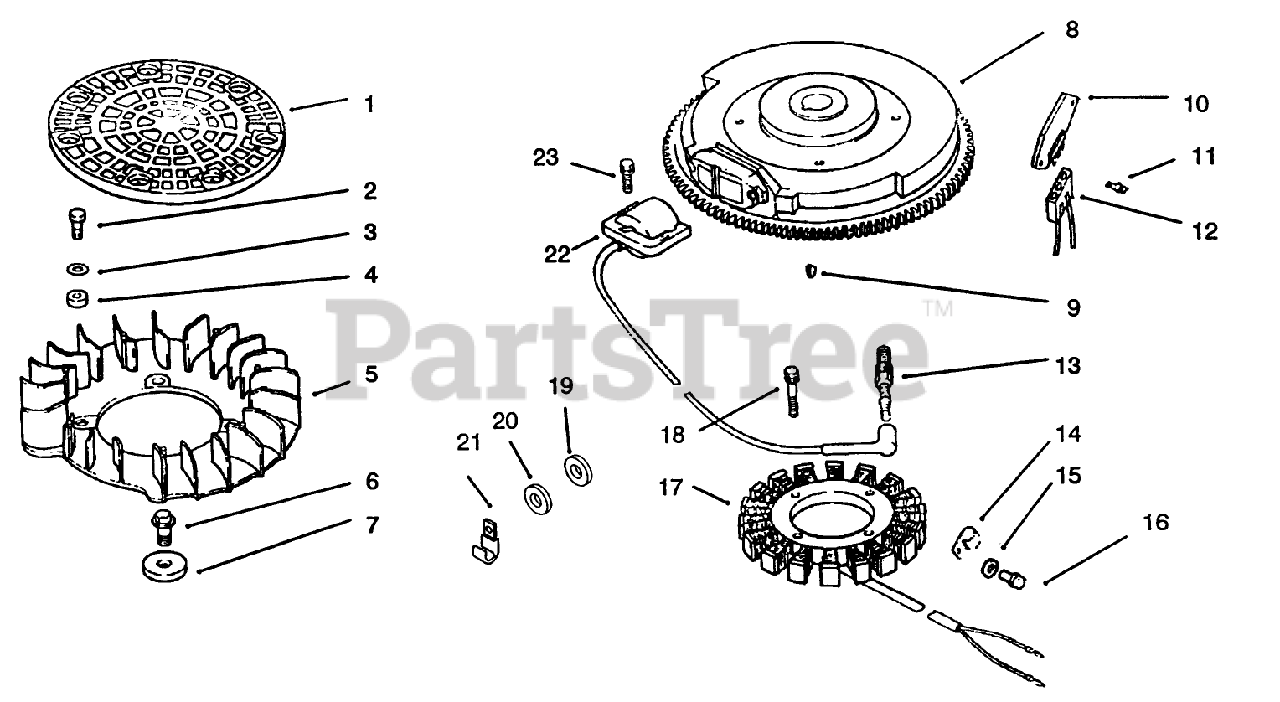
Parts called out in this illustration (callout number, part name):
1	Screen-Grass (Only On: 72103, 72083)
3	Washer
4	Spacer-Fan (Only On: 72103)
5	Fan (Only On: 72103, 72083)
7	Spacer-Fan
8	Flywheel ASM (Only On: 72103, 72083)
10	Rectifier-Regulator
12	Connector
13	Spark Plug
16	Screw
17	Stator-15 amp
19	Washer
20	Washer
22	Module-Ignition
